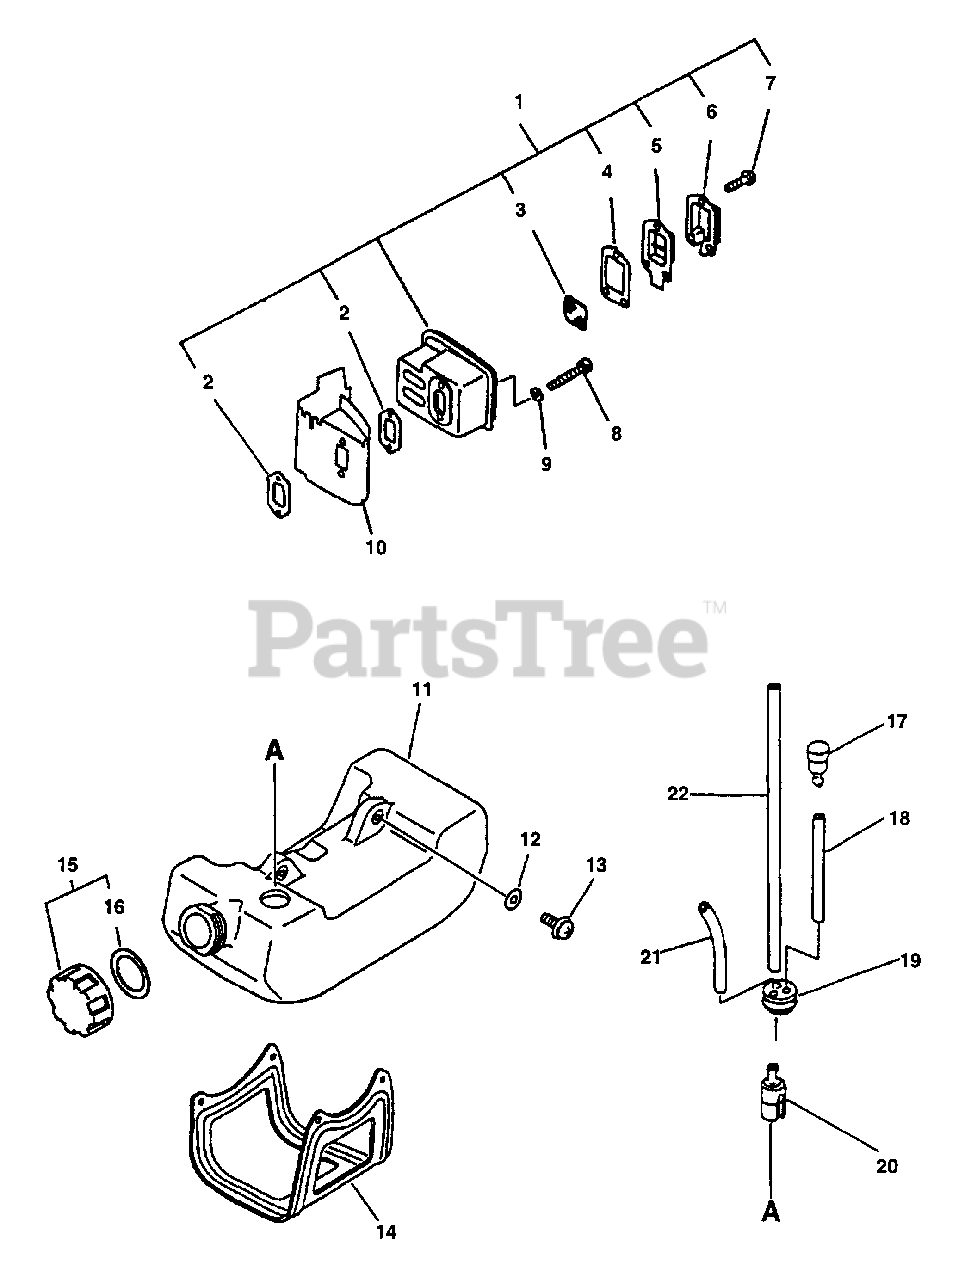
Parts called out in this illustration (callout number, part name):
1	MUFFLER ASSY
2	GASKET, EXHAUST
3	SCREEN, SPARK ARRESTOR
4	GASKET, EXHAUST
5	GASKET, EXHAUST - INNER
6	GUIDE, EXHAUST - OUTER
7	SCREW - 4X10
8	SCREW - 5X55
9	WASHER - 5
10	COVER, EXHAUST
11	TANK, FUEL
12	WASHER - 5
13	SCREW - 5X16
14	GUARD, FUEL TANK
15	CAP ASSY
16	GASKET, CAP
17	VENT, FUEL TANK
18	PIPE - 3X5X70 -- BLACK
19	GROMMET
20	FILTER, FUEL
21	PIPE - 3X6X80 -- CLEAR
22	PIPE - 3X5X180 -- BLACK
